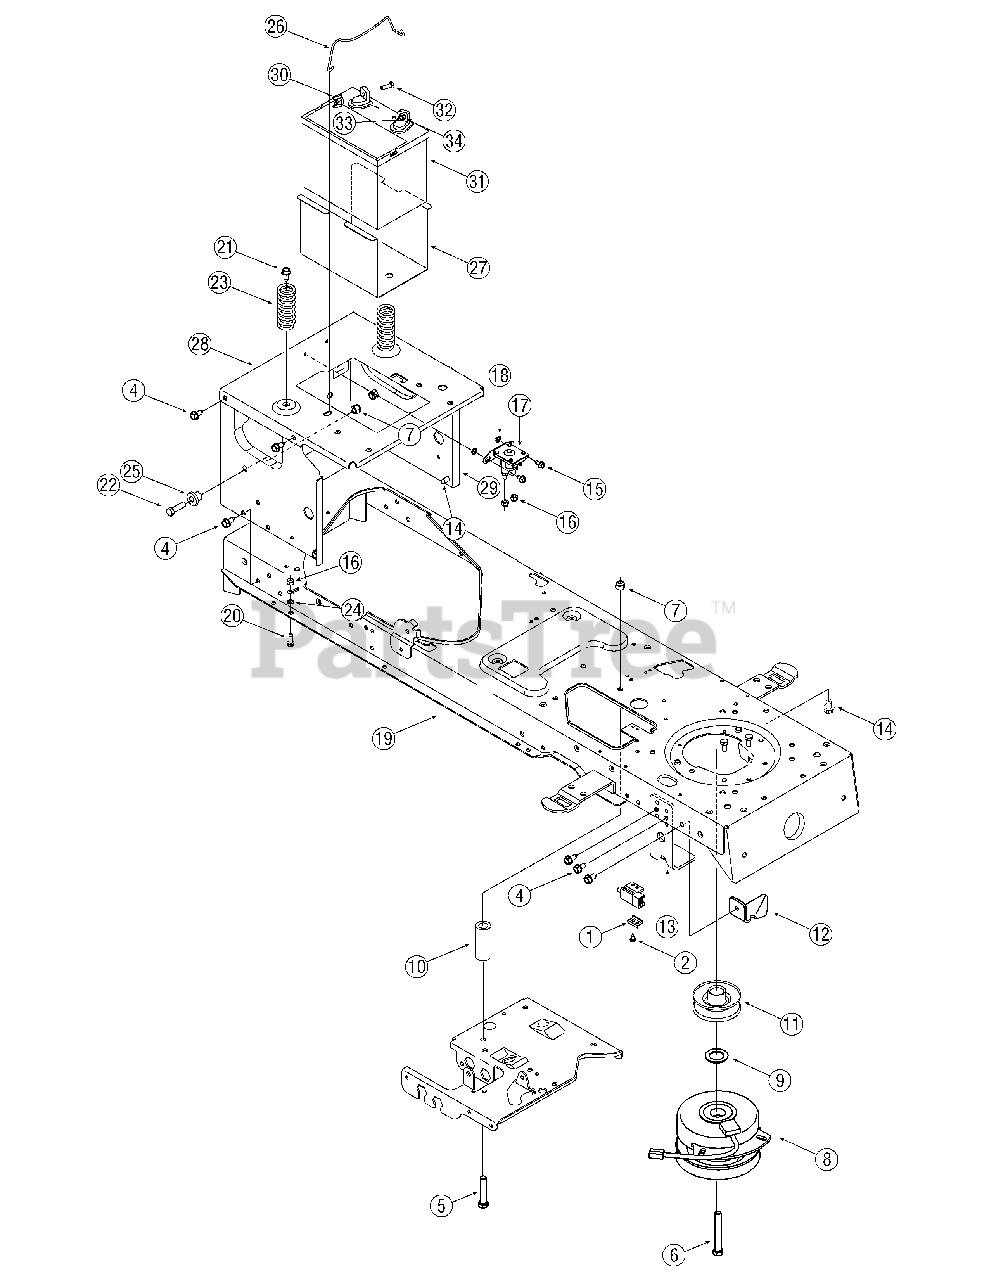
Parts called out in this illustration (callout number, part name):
1	Switch Plate
2	Screw, #10-16 x.500
3	Interlock Switch
4	AB Screw 5/16-12 x 0.75
5	Hex Head Screw 3/8-16 x 2.50
6	Screw, 7/16-20, 3.25, Gr5
7	Nut, Flange Lock, 3/8-16, GrF
8	Electric PTO Clutch
10	Spacer,.385 ID x.635 OD x 1.54
11	Engine PTO Pulley
14	Screw 5/16-18 x .50
15	Screw, 1/4-20, 0.50
16	Nut, Flange Lock, 1/4-20, GrF
17	Solenoid, 12V, 100 Amp
18	Washer, Lock, 1/4, External
21	LD Screw 5/16-18 x 0.75
22	Screw, 3/8-16, 1.25, Gr5
23	Spring, Compression
24	Lock Washer 1/4
25	Spacer, Shoulder,.38 x 1.0 x .70
26	Hold Rod, Battery
31	Battery, 235 CCA
32	Screw, Shoulder
33	Carriage Screw 1/4-20 x .75
